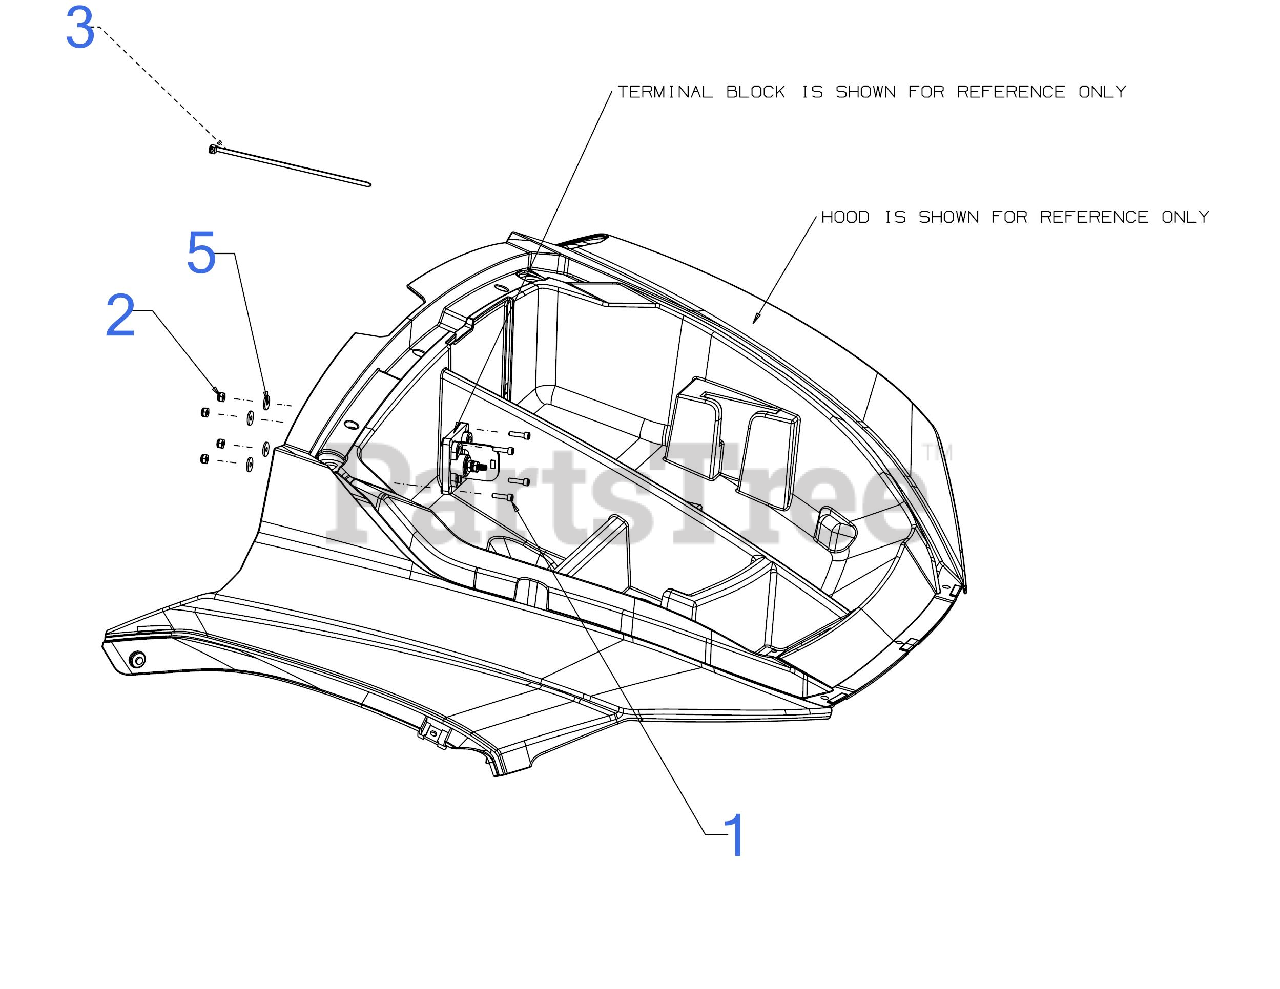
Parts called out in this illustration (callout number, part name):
1	SCREW 10-24 x .750
3	7" CABLE TIE
5	FLAT WASHER .194x.620x.063
